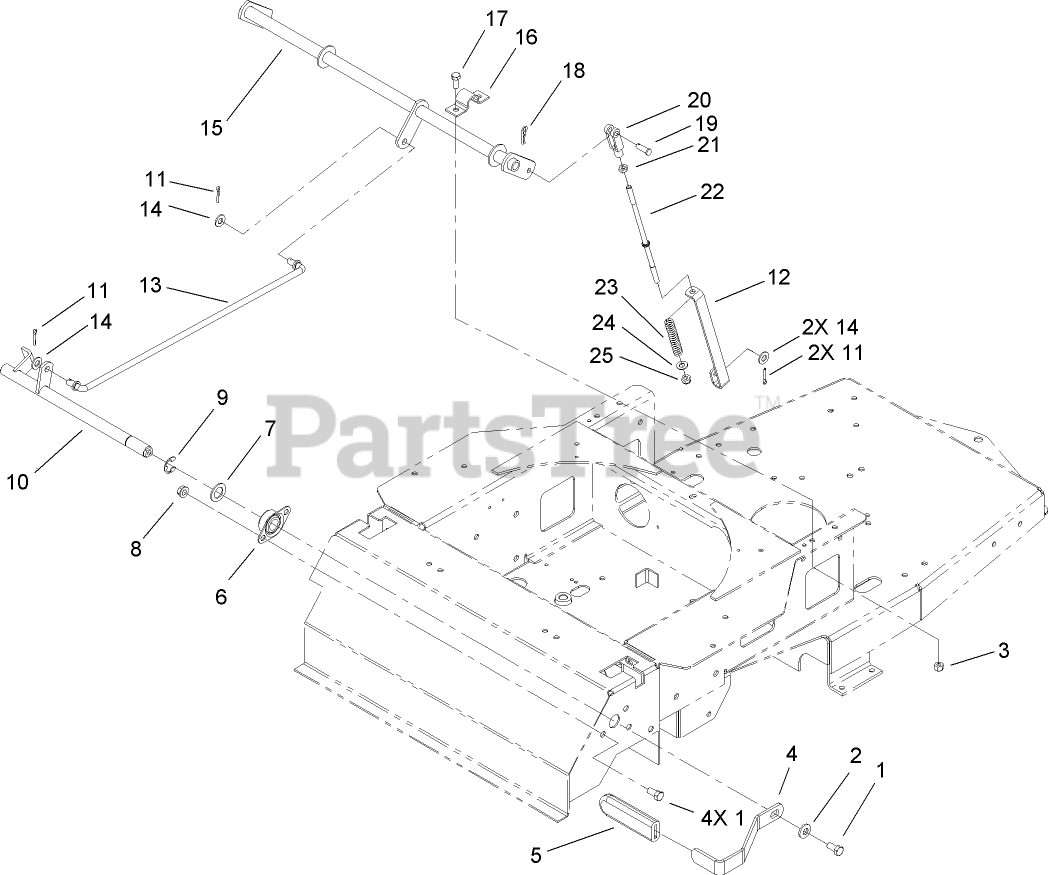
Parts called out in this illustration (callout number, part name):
1	SCREW-HH
2	WASHER-BELLEVILLE
3	NUT-LOCK, NI
4	HANDLE-BRAKE, PARK
5	GRIP-LEVER
6	BEARING-FLANGE, SIDE
7	WASHER
8	NUT-HHF, WHIZ
9	E-RING
10	BRAKE SHAFT ASM
11	PIN-COTTER
12	BRACKET-SPRING, BRAKE
13	ROD-BRAKE, UPPER
14	WASHER-FLAT
15	SHAFT-BRAKE
16	CLAMP-PIVOT, HOC
17	SCREW-HH
18	PIN-COTTER
19	PIN-CLEVIS
20	YOKE-ADJUSTABLE
21	NUT-HEX
22	ROD-BRAKE, UPPER
23	SPRING
24	WASHER-PLAIN
25	NUT-LOCK
